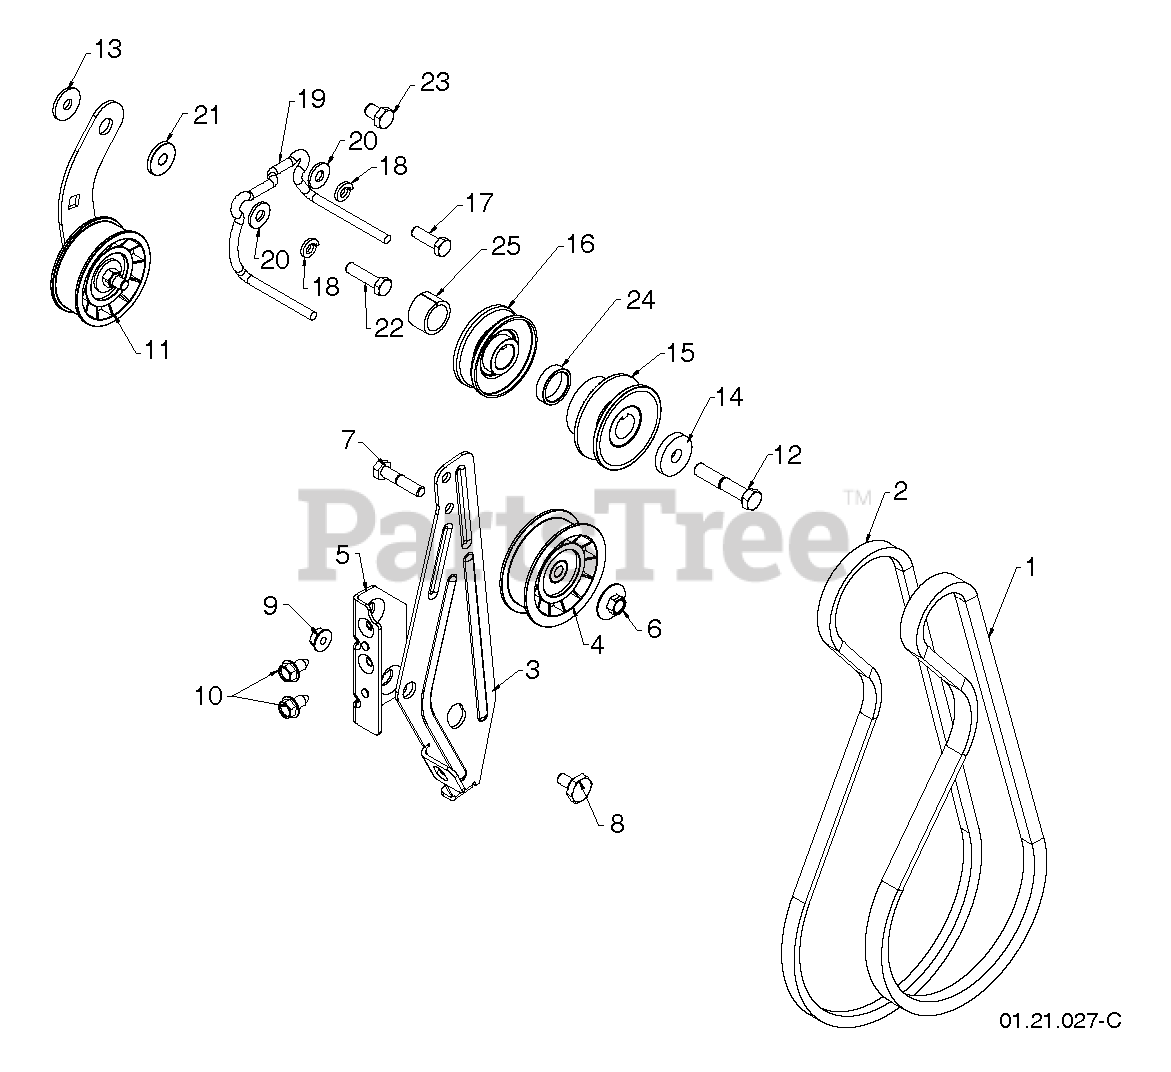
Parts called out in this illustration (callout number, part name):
1	V-BELT.IMPELLER
2	V-BELT.TRACTION
3	ARM.IDLER BRAKE.CLEAR.ZINC
4	PULLEY.W/SPACER.2.75
5	BRACKET.IDLER.PIVOT.ZINC
6	NUT.FLANGE.HEX.5/16X18.BLACK
7	HEX BOLT
8	BOLT.SHOULDER.1/2X12
9	NUT.LOCK.5/16-18
10	BOLT.5/16HEX.WHS.HD
11	ARM.ASM.TRACTION.IDLER.
12	BOLT.BLADE
13	STEEL WASHER
14	WASHER.400X1.25X5.
15	PULLEY IMPELLER.ASM.2.60_.75 B
16	PULLEY,ENGINE TRACTION DRIVE
18	LOCKWASHER
19	GUIDE.BELT.CHAIN.LS.SNOW
20	WASHER.20X8.5
21	BUSHING.BRAKE.ARM
22	CAPSCREW.HEXHD.5/16X1.25.
23	SCREW.3/8-16 X .750 (2 2)
24	SPACER.ENGINE.PULLEY
25	SPACER AXLE
